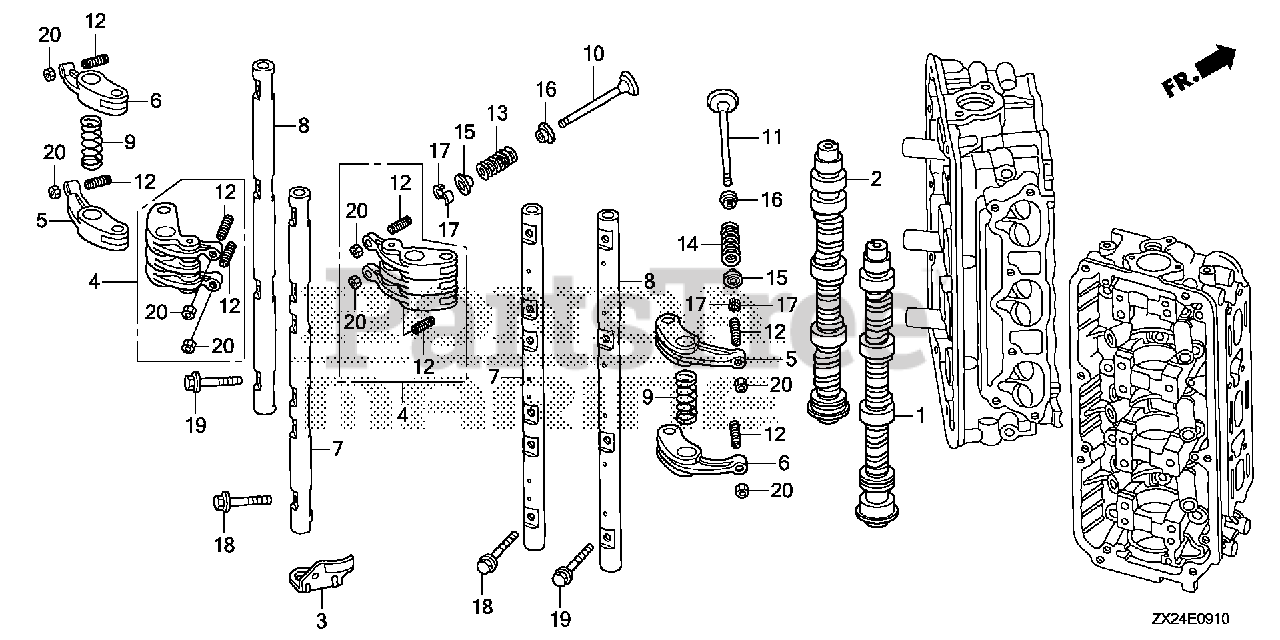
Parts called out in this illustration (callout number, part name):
1	CAMSHAFT, R.
2	CAMSHAFT, L.
3	ARM, FUEL PUMP ROCKER
4	ARM ASSY., IN. ROCKER
5	ARM A, EX. ROCKER
6	ARM B, EX. ROCKER
7	SHAFT, IN. ROCKER ARM
8	SHAFT, EX. ROCKER ARM
9	SPRING, ROCKER ARM
10	VALVE, IN.
11	VALVE, EX.
12	SCREW, TAPPET ADJUSTING
13	SPRING, VALVE (PINK) (NIPPON HATSUJO)
14	SPRING, EX. VALVE (YEL/GRN) (ASSOCIATE)
15	RETAINER, VALVE SPRING
16	SEAT, VALVE SPRING
17	COTTER, VALVE (FUJI VALVE)
18	BOLT, FLANGE (8X30)
19	BOLT, FLANGE (8X40)
20	NUT, TAPPET ADJUSTING
